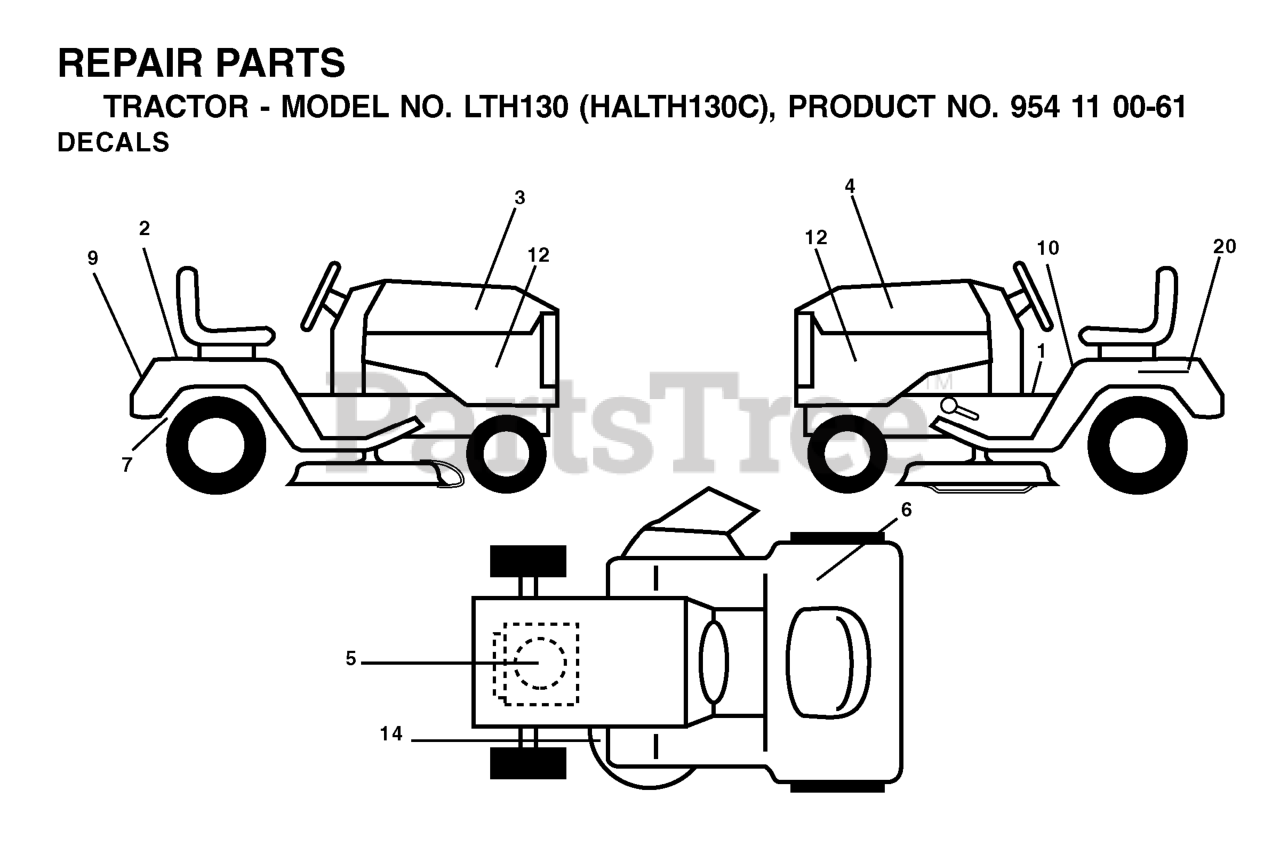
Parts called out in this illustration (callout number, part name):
2	DECAL
3	DECAL HOOD RH
4	DECAL HOOD LH
5	DECAL HP ENGINE
6	DECAL 80 DBA
7	DECAL BY PASS LT HYDRO
9	DECAL FENDER HUSQ
12	DECAL PNL SIDE
14	DECAL V BELT SCHEMATIC
20	DECAL BTRY SYMBOLS
